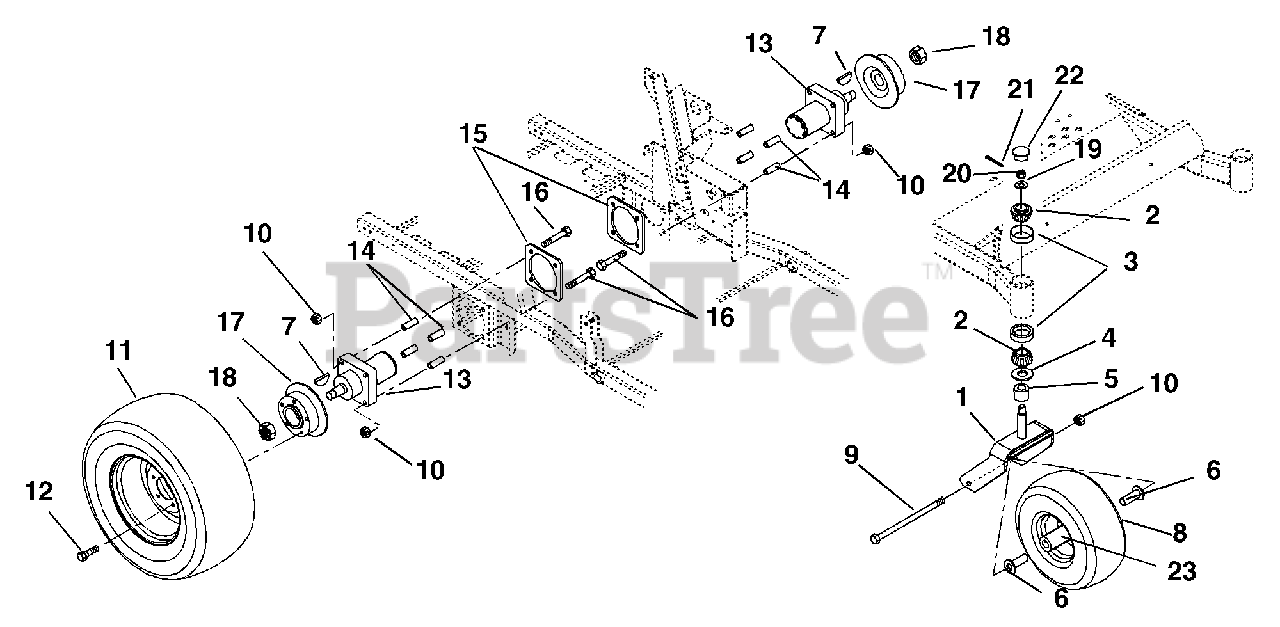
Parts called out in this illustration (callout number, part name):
1	Fork
2	Bearing, Cone with Grease
3	Bearing, Cup 1.98 x .420
4	Bearing Seal 1.5 x 2 x .18
5	Spacer, PM, 1.03 I.D. x 1.5 O.D. x .375
6	Spacer, Wheel
7	Key, Woodruff .31 x 1.00
8	Wheel/Tire Assembly
8	Tire, 15 x 6-6
9	Bolt, Hex .50-13 x 9.00 Grade 5
10	Nut, Locking Top Flange .50-13
11	Wheel, Tire Assembly 23 x 10.50 -12 (080, 081, 082)
11	Tire 23 x 10.50 (078, 079, 080, 081, 082, 311)
11	Wheel, Tire 23 x 10.50 - 12 Multi-Trac (078, 079, 081, 311)
11	Wheel, Tire Assembly 23 x 9 50-12 (077, 310)
11	Tire, 23 x 9.50-12 Multitrac (077, 310)
12	Bolt, Lug Grade 8; .50-20 Unf x .75 Long 60 Degree
13	Hydraulic Wheel Motor
14	Bushing, Sleeve .513 x .748 x 2.13
15	Plate, Motor Support
16	Bolt, Hex .50-13 x 5.00 Grade 5
17	Hub and Disc
18	Nut, Lock Jam Patch
19	Washer, Flat Steel .755 x 1.375 x .062
20	Nut, Slotted .75-16
21	Pin, Cotter .16 x 1.00
22	Cap, Dust
23	Bearing, 25MM I.D. x 52MM OD x 15MM
